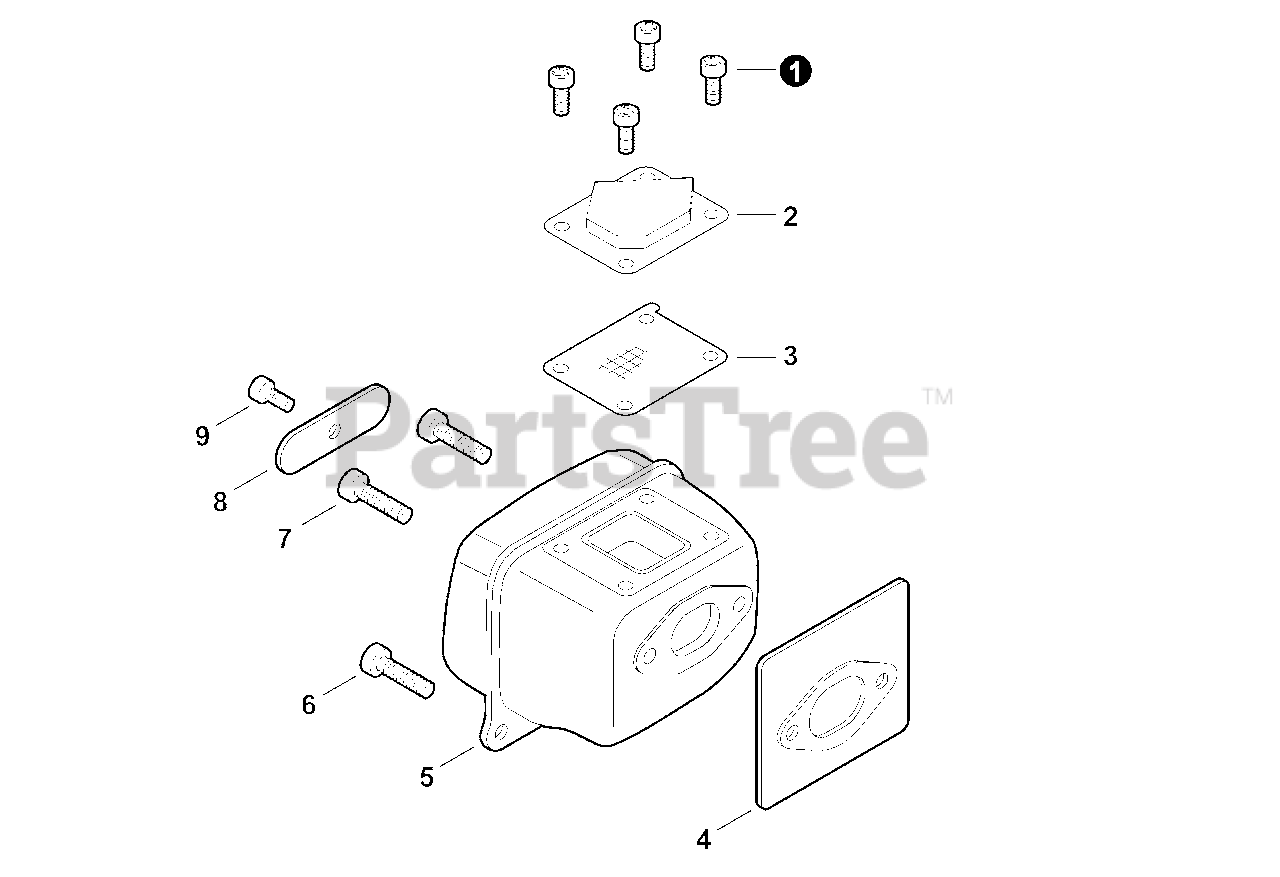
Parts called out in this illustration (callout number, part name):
1	BOLT, TORX 4×8
2	GUIDE, EXHAUST
3	SCREEN, SPARK ARRESTER
4	GASKET, EXHAUST
5	MUFFLER
6	BOLT, TORX 5×25
7	BOLT, TORX 5×20
8	PLATE, MUFFLER
9	BOLT, TORX 4×8
